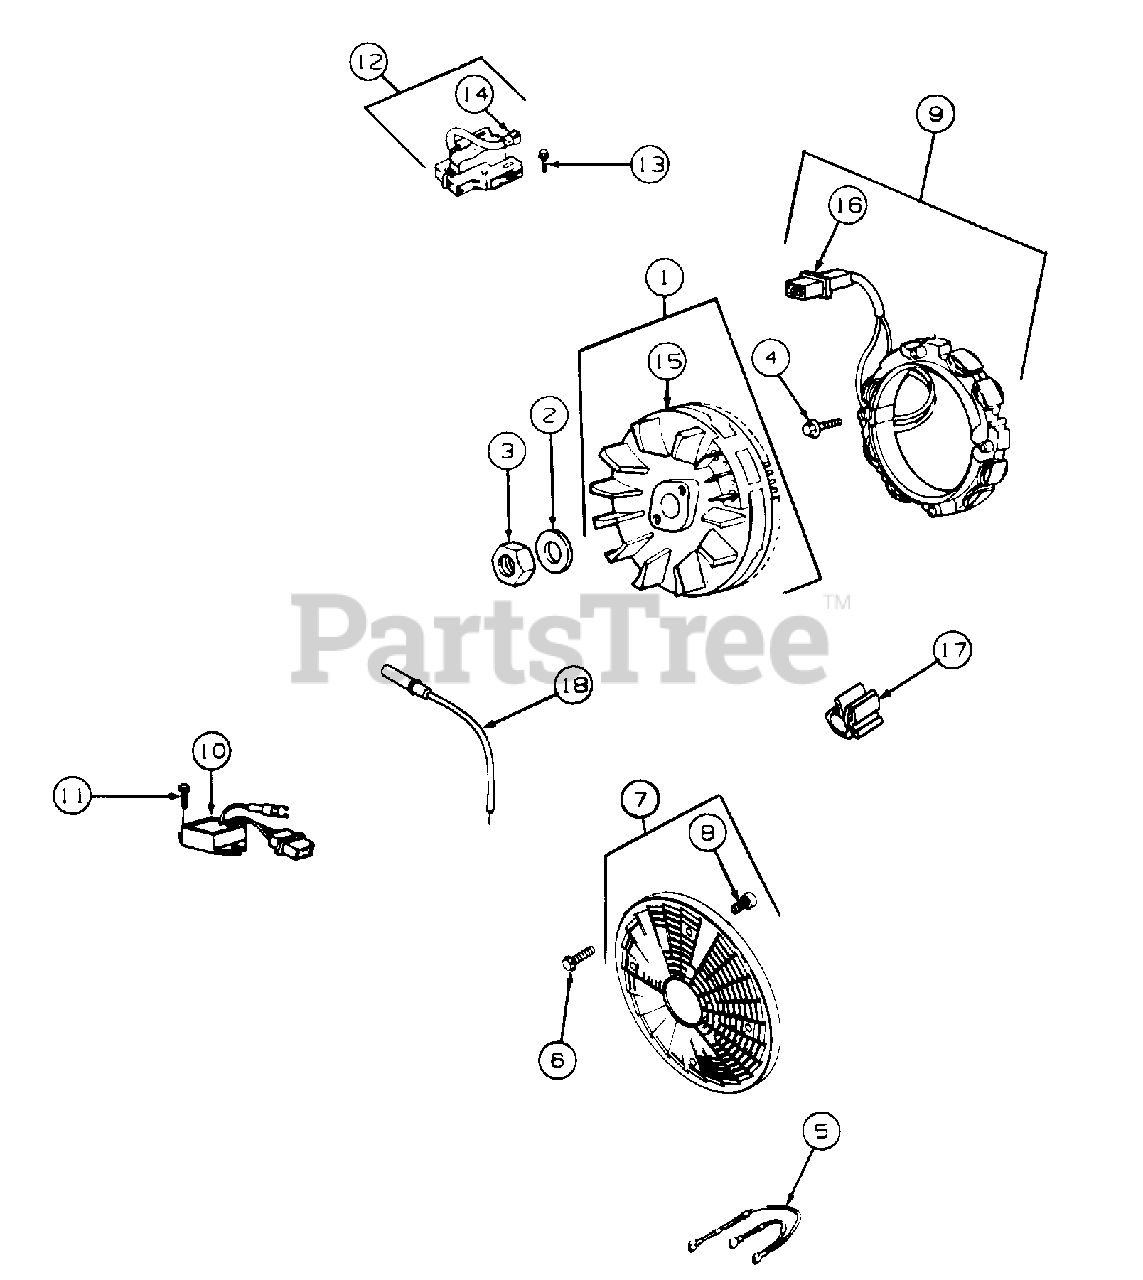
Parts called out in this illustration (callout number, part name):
1	Flywheel & Ring Gear
2	Washer, Spring
4	Screw, Mounting
5	Wire, Ground
6	Screw, Sems
7	Screen, Rotating
8	Spacer
9	Stator, 16 Amp
10	Regulator
11	Screw, Mounting
12	Armature
13	Screw, Mounting
14	Terminal
15	Gear, Flywheel Ring
16	Diode & Connector Assy
17	Clip, Wire
18	Harness, Alternator
